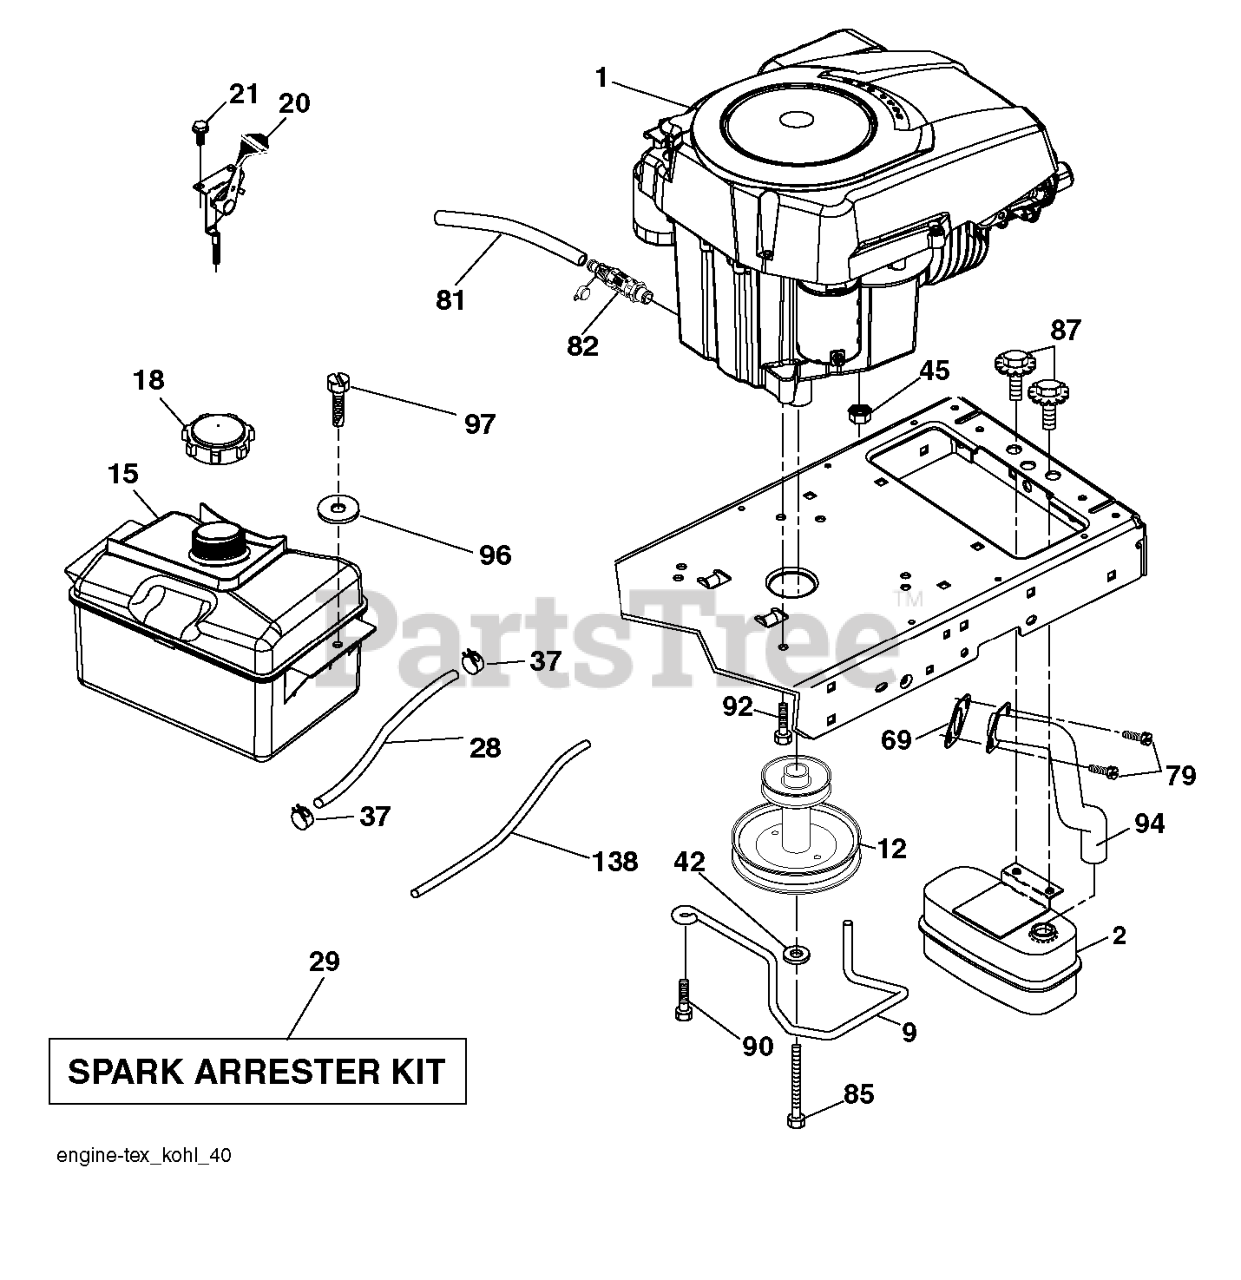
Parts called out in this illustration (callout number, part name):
2	MUFFLER.SINGLE.CYL.KOHL/B&S
9	KEEPER.BELT.ENGINE.4.2
12	RP_PULLEY ENGINE
15	TANK.ASM.FRT.2.5 GAL.W/CAP.EPA
18	CAP.2.25'.VENTED.TETHER .EPA
20	CONTROL.TH/CK.COBRA.KO
21	SCREW.#10 X 0.750.BOS
28	LINE.FUEL.20"FRONT.EMI
29	KIT.SPARK ARRESTOR 794945 B&S
37	HOSE CLAMP
42	LOCKWASHER
45	NUT
69	GASKET.EXHAUST.KOHLER
79	SCREW.SOCKET HD.5/16-1
81	TUBE, DRAIN OIL ASM.
82	VALUE.OIL.DRAIN
85	BOLT HEX 7/16-20X4-1/4"
87	BOLT 5/1618UNC X 3/4 W/ SEMS
90	SCREW 3/8-16X1
92	SCREW 3/8-16X1
94	RP.TUBE.EXHAUST.KOHL.COURAGE
97	SCREW HEXWSHR 1/4-20X3/4
138	RP PURGE LINE
